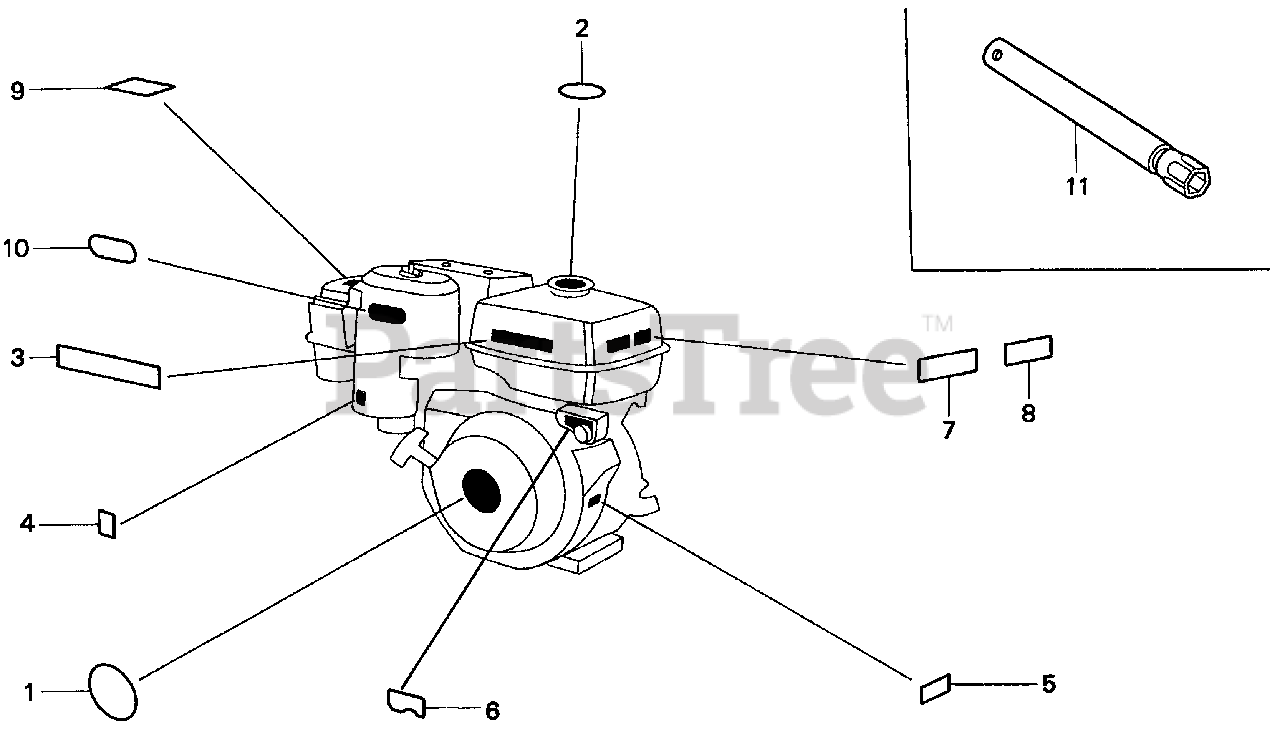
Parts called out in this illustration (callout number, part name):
1	EMBLEM
2	MARK, CAUTION (EXTERNAL)
3	LABEL, CAUTION
4	MARK, CHOKE (EXTERNAL)
5	LABEL, SPECIFICATION (EXTERNAL)
6	MARK, OIL ALERT (GERMAN)
6	MARK, OIL ALERT (FRENCH)
7	MARK, OIL ALERT (EXTERNAL)
8	MARK, OIL ALERT (E)
9	LABEL, AIR CLEANER CAUTION
10	MARK, AIR CLEANER SALES POINT
12	LABEL (E-SPEC)
